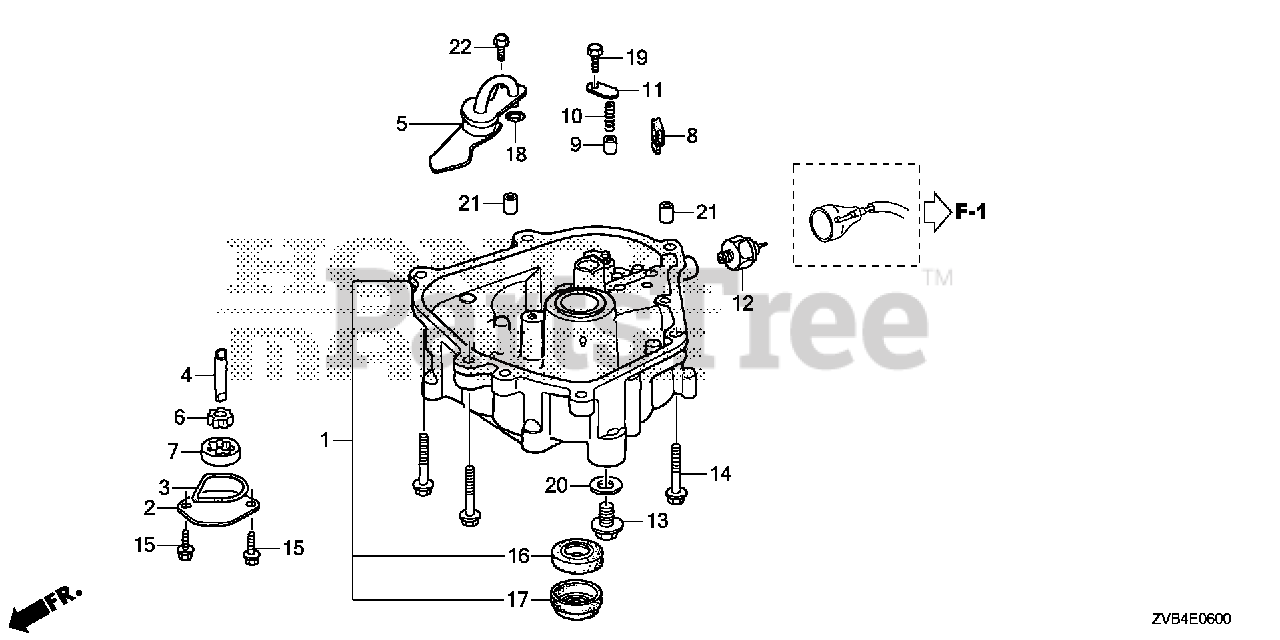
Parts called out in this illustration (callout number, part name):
1	PAN ASSY., OIL *NH8* (DARK GRAY)
2	COVER, OIL PUMP
3	O-RING, PUMP COVER
4	SHAFT, OIL PUMP
5	STRAINER, OIL
6	ROTOR, OIL PUMP (INNER)
7	ROTOR, OIL PUMP (OUTER)
8	RUBBER, OIL RETURN
9	VALVE, CHECK
10	SPRING, CHECK VALVE
11	PLATE, CHECK VALVE
12	SWITCH ASSY., OIL PRESSURE
13	BOLT, DRAIN PLUG (12MM)
14	BOLT, FLANGE (8X32)
15	BOLT, FLANGE (6X12)
16	OIL SEAL (25X38X7)
16	OIL SEAL (25X38X7) (ARAI)
17	SEAL, COUPLING (25X40X14)
18	O-RING (9.6X2.6) (ARAI)
19	BOLT, HEX. (6X12)
20	WASHER, DRAIN PLUG (12MM)
21	PIN A, DOWEL (8X14)
22	BOLT, FLANGE (6X12)
